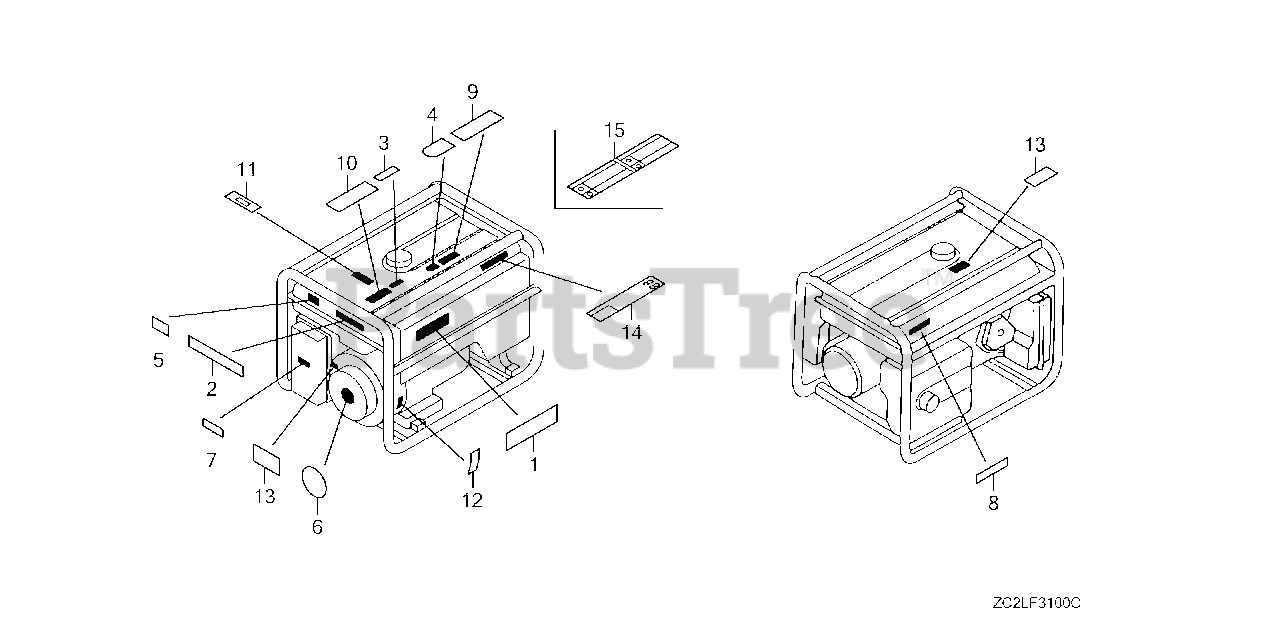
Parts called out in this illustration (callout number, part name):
1	EMBLEM (EM5000S)
2	PLATE, CAUTION
3	LABEL, RAIN WARNING (ENGLISH)
4	MARK, CAUTION (ENGLISH/FRENCH/SPANISH)
5	MARK, CHOKE
6	MARK, OIL ALERT
7	MARK, AIR CLEANER (ENGLISH)
8	MARK, EX. CAUTION (ENGLISH/FRENCH)
9	MARK, CAUTION (ENGLISH/FRENCH/SPANISH)
10	LABEL, CONNECT WARNING (ENGLISH)
11	PLATE, FUEL INDICATION
12	MARK, OIL CAUTION
